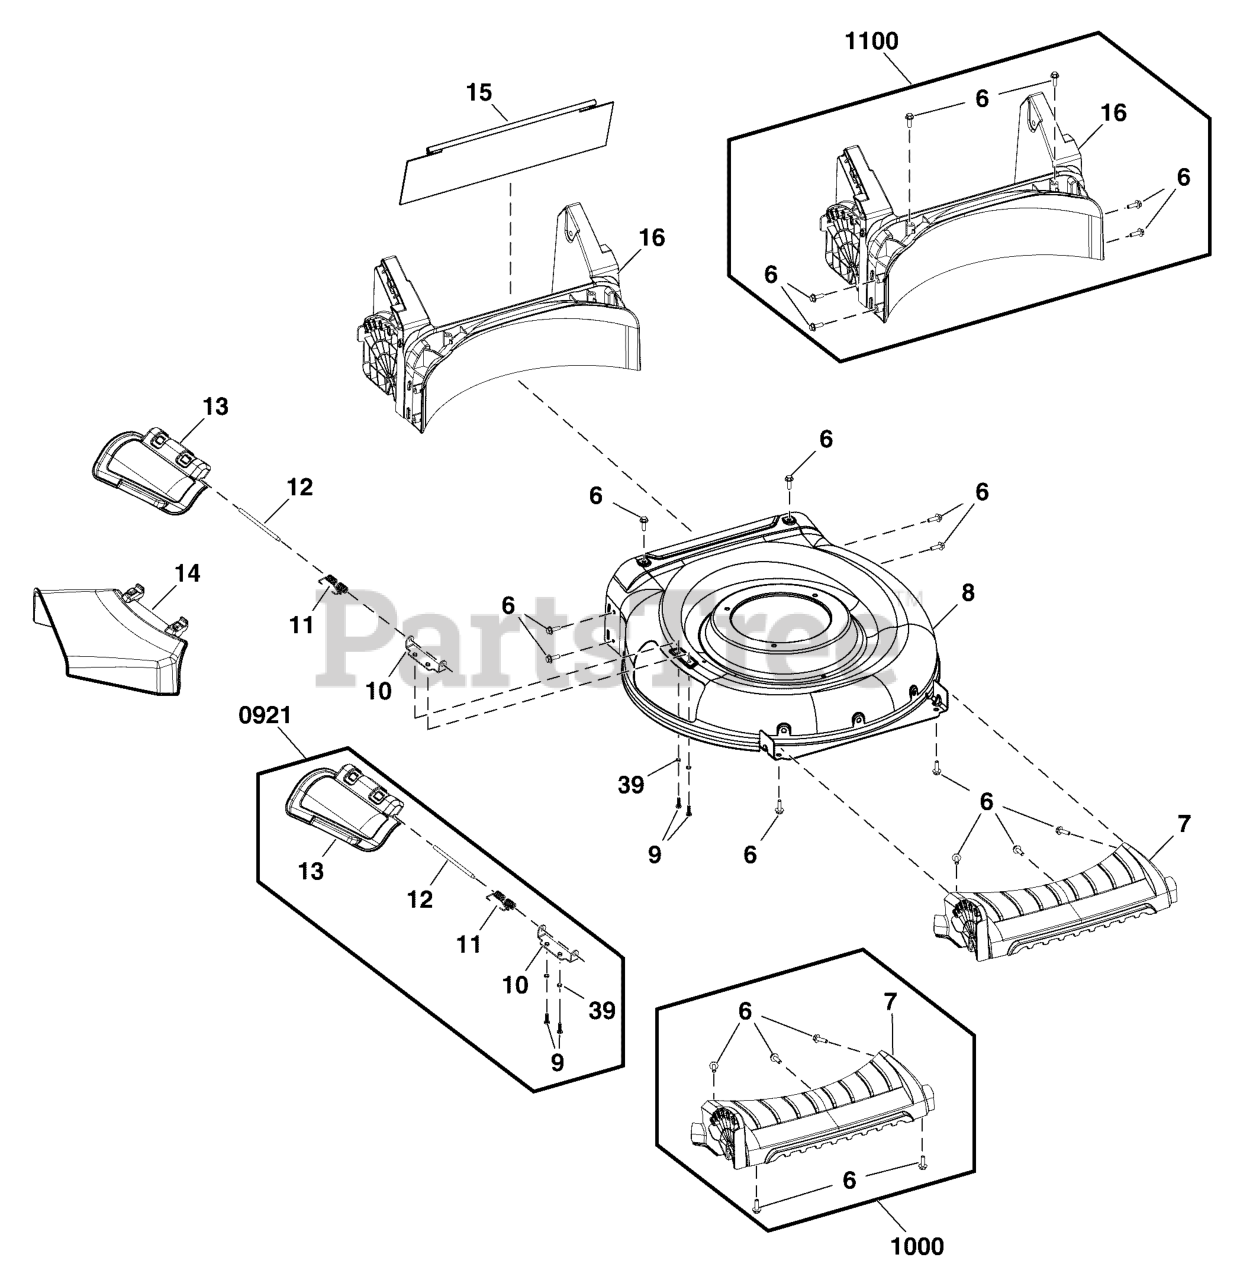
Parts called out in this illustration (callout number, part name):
6	SCREW, Hex Head
7	HOUSING, Front
8	DECK
9	SCREW
10	BRACKET, Deflector
11	SPRING, Deflector
12	SHAFT, Deflector
13	COVER, Mulch
14	DEFLECTOR
15	COVER, Dust
16	HOUSING, Rear
39	WASHER
0921	KIT, Mulching
1000	KIT, Housing, Front
1100	KIT, Housing, Rear
